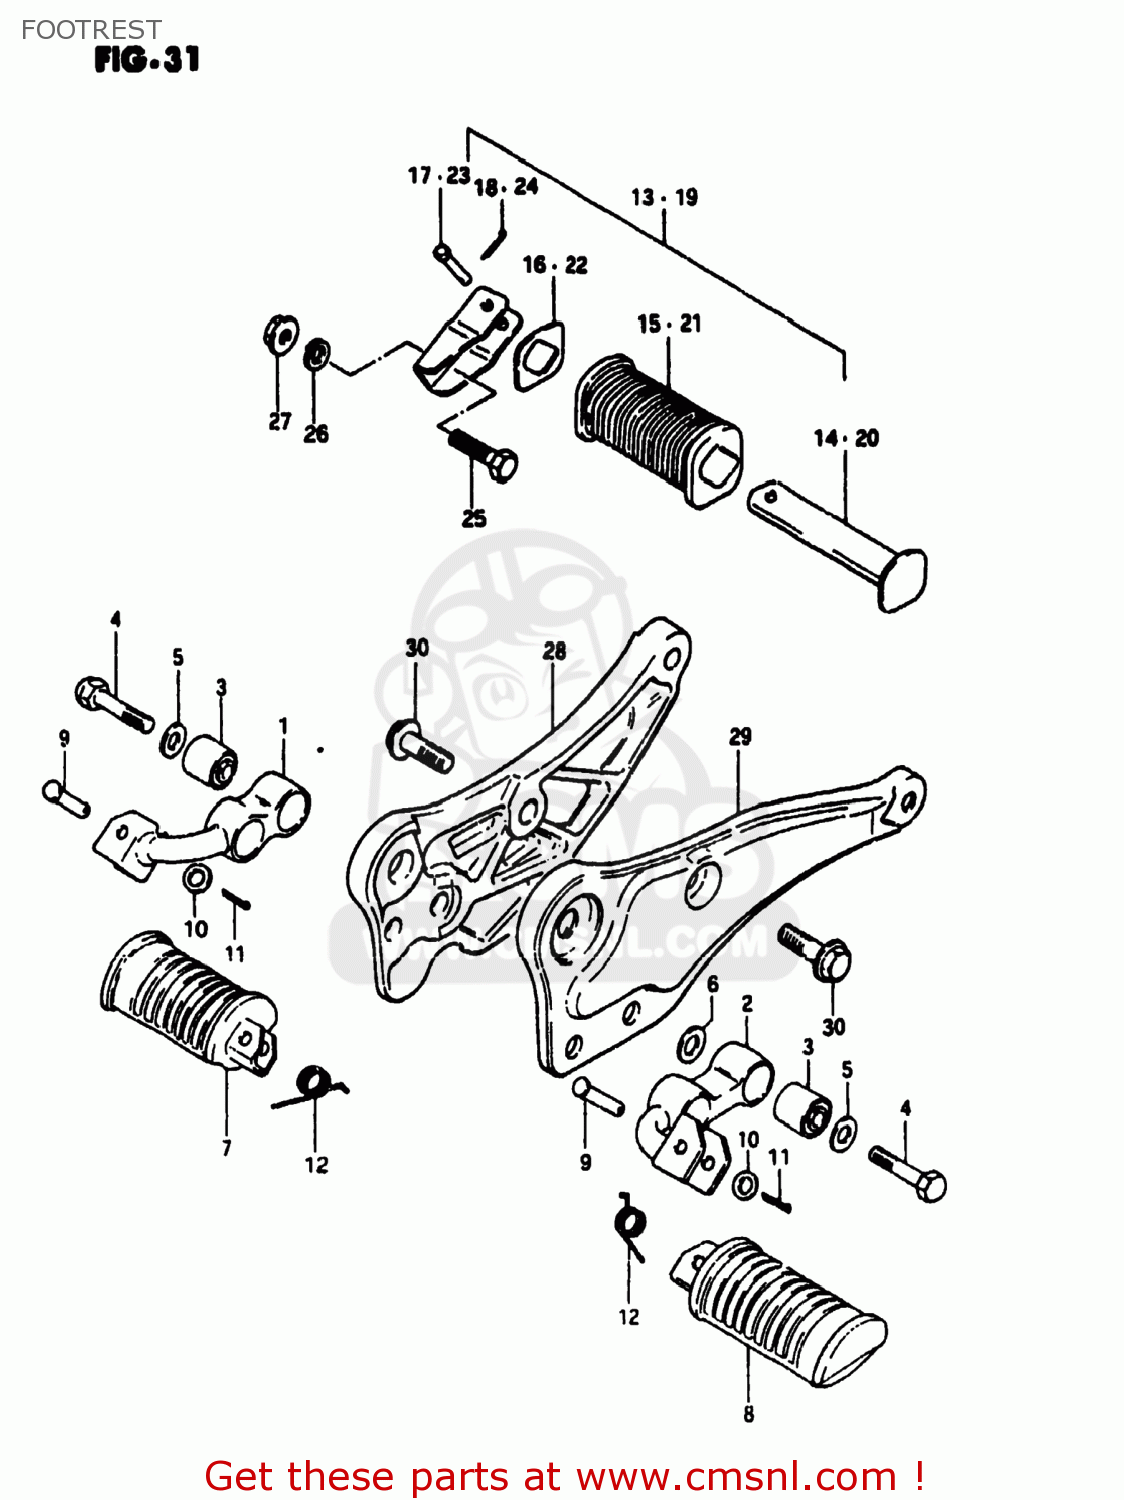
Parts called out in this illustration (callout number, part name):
1	BAR,FRONT FOOTREST
2	BAR,FRONT FOOTREST,LEFT
3	BUSH
4	BOLT(10X50)
5	WASHER
6	WASHER
7	RUBBER,FRONT FOOTREST
8	FOOTREST
9	PIN
10	WASHER
11	PIN
12	SPRING
13	FOOTREST ASSEMBLY,REAR
14	BAR,REAR FOOTREST
15	RUBBER,REAR FOOTREST
16	WASHER,FOOTREST RUBBER
17	PIN
18	PIN
19	FOOTREST ASSEMBLY,REAR,LEFT
20	BAR,REAR FOOTREST,LEFT
21	RUBBER,PILLION FOOTREST
22	WASHER,FOOTREST RUBBER
23	PIN
24	PIN
25	BOLT,M10X1.25X
26	LOCK WASHER
27	NUT
28	BRACKET, MUFFLER RH
29	BRACKET, MUFFLER LH
30	BOLT
